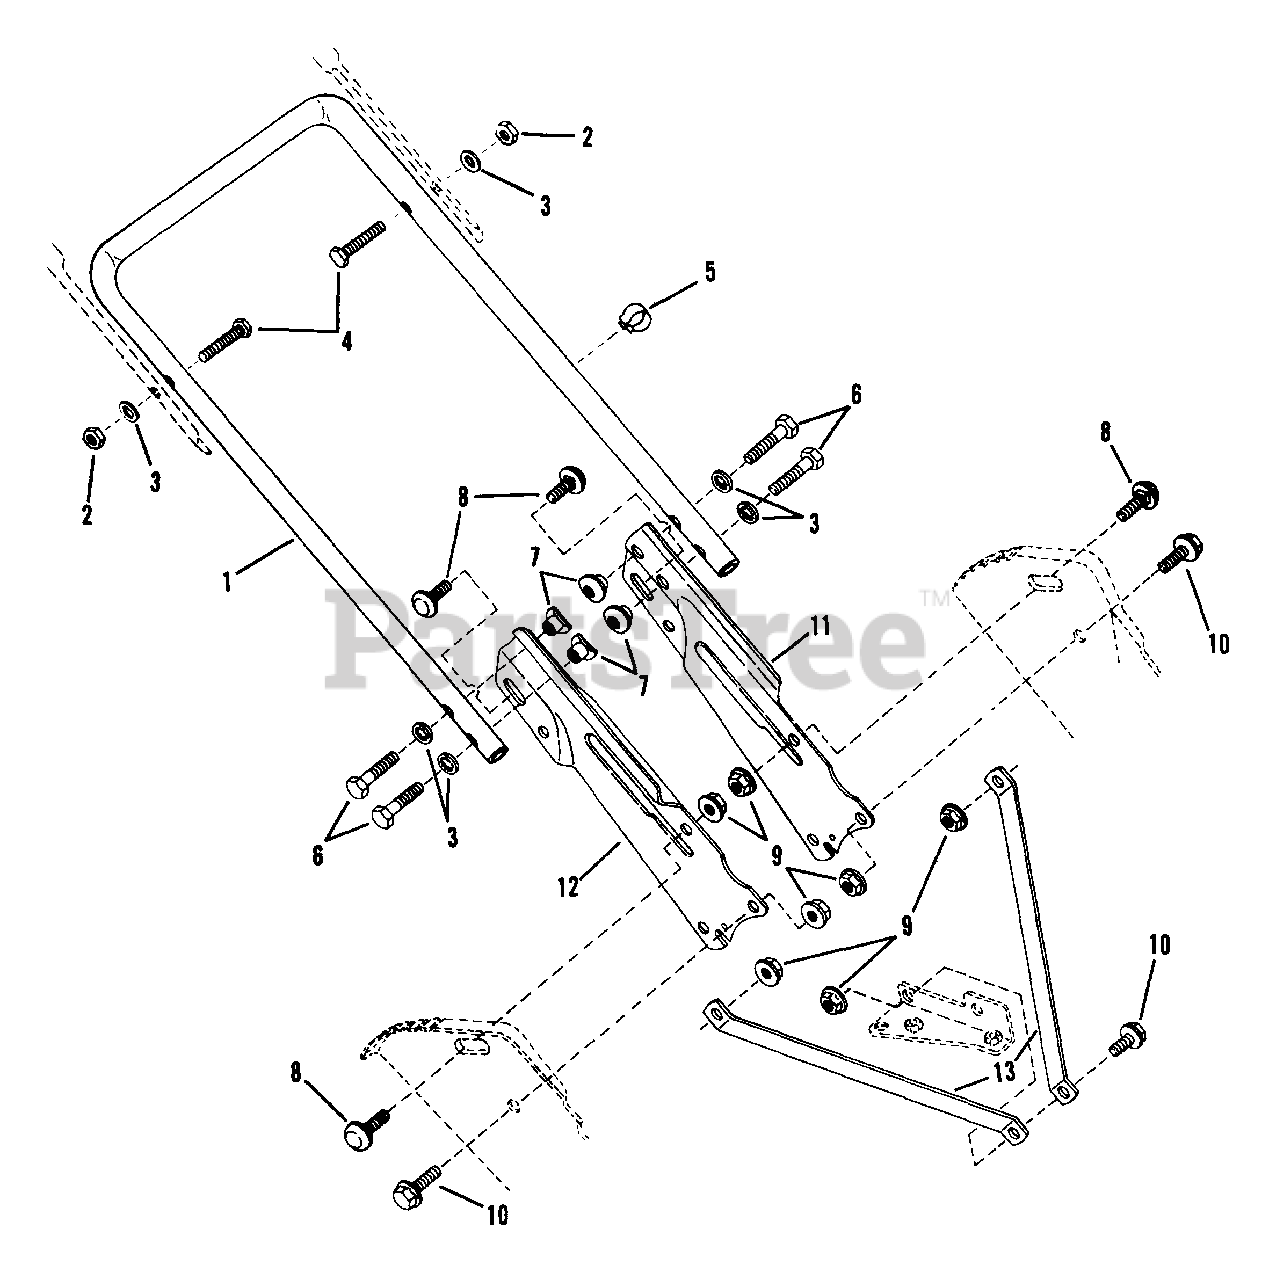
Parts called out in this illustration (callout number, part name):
1	HANDLE, Middle
2	NUT, 1/4-28 Hex
3	WASHER, 1/4 Internal Tooth Lock
4	SCREW, 1/4-28 x 1 3/8 Hex Head Cap (Gr. 5)
5	CLIP
6	SCREW, 1/4-20 x 1" Hex Head Cap (Gr. 5)
7	T-NUT, 1/4-20 Curve Head
8	BOLT, 5/16-18 x 5/8" Carriage
9	NUT, 5/16-18 Hex Flange Lock
10	BOLT, 5/16-18 x 3/4" Hex Flange Lock
11	MOUNT, L.H. Handle
12	MOUNT, R.H. Handle
13	STRAP, Handle
